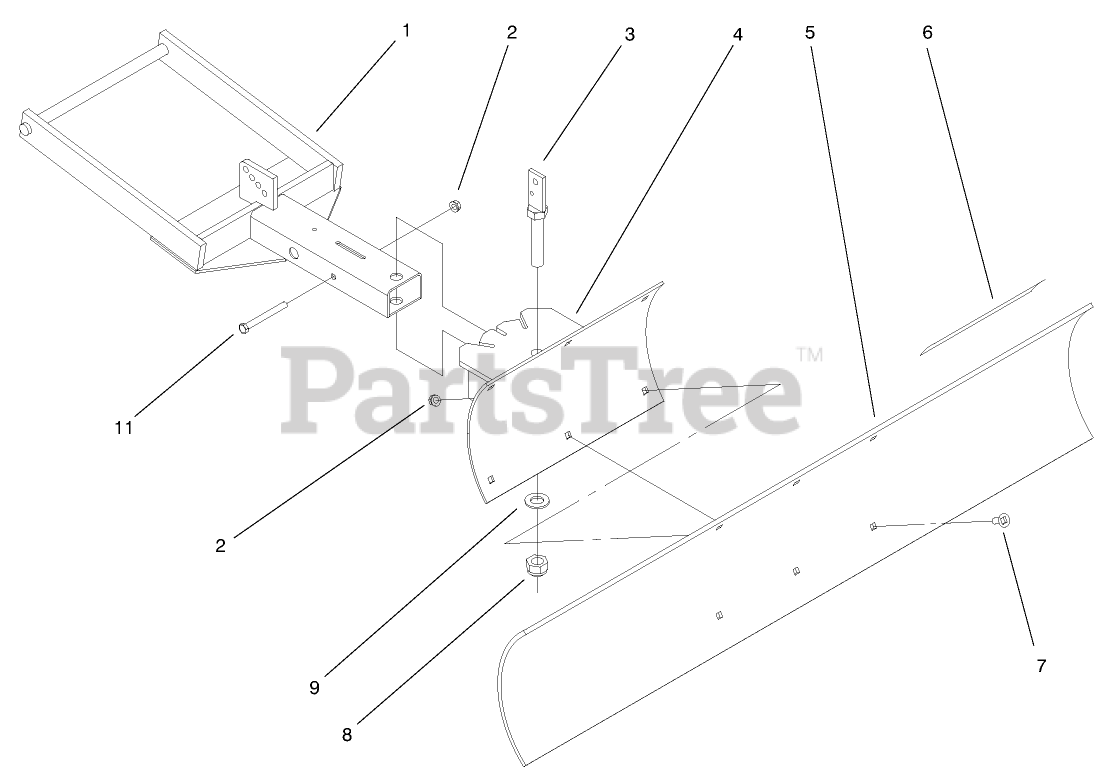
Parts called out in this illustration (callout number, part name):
1	Wa-Frame
2	NUT-LOCK, NI
3	Ass-y-Pivot Bolt
4	ASS'Y-QUADRANT
5	50"-Blade
6	DECAL-ATTACHMENT
7	BOLT-CARR
8	NUT-LOCK
9	WASHER-FLAT
11	SCREW-HH
